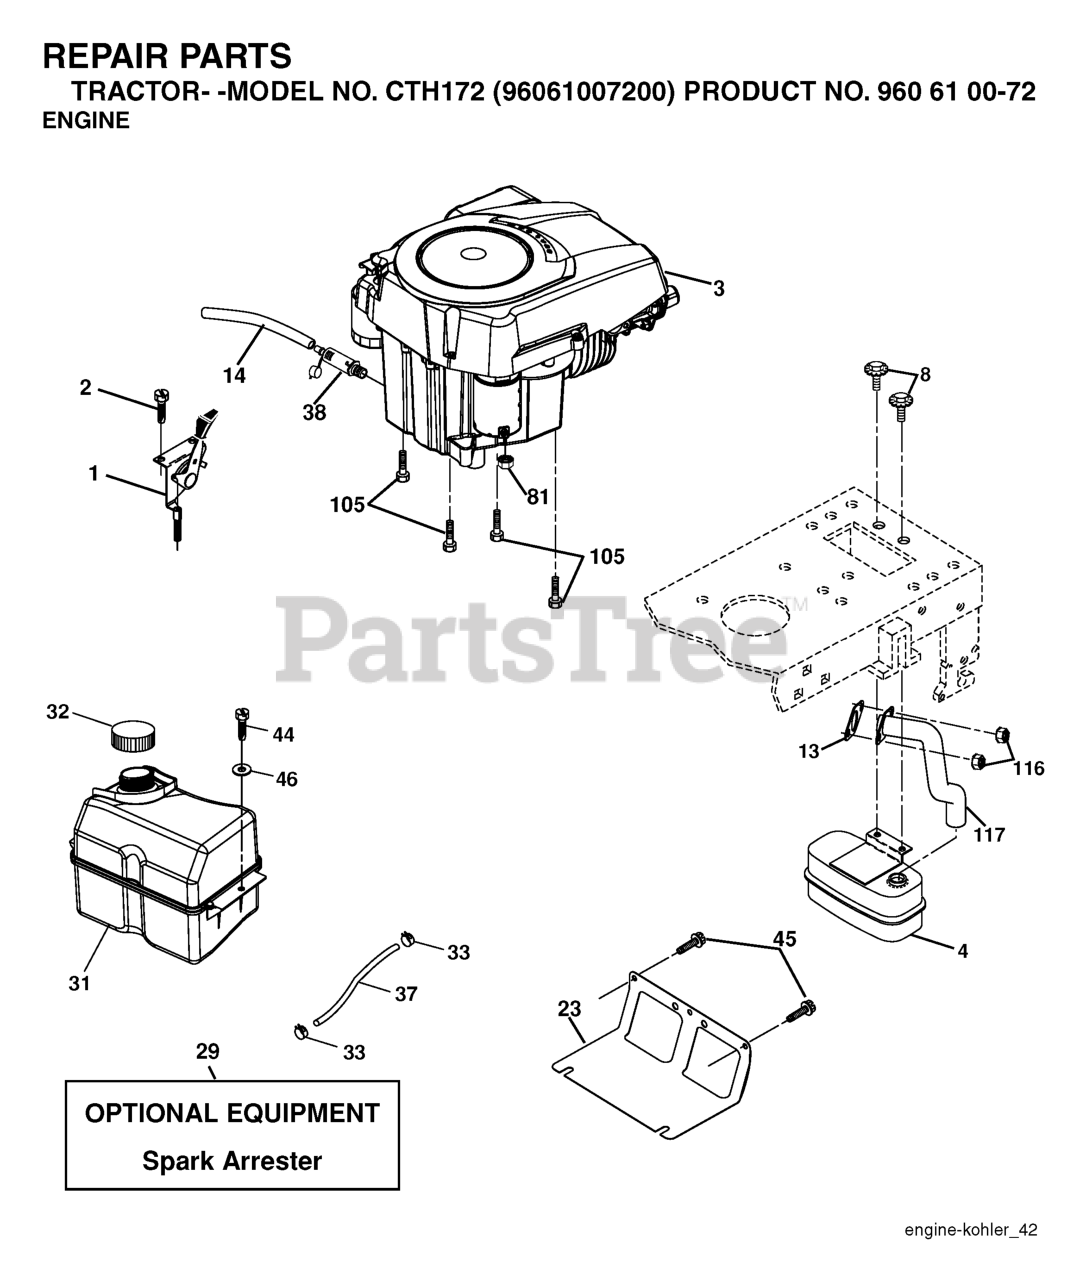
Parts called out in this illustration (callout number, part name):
1	CONTROL.THROTTLE.LT/YT
2	SCREW
4	MUFFLER.SINGLE.CYL.KOHL/B&S
8	BOLT.5/16-18UNCX3/4 W/SEMS.BLK
13	GASKET.EXHAUST.KOHLER
14	TUBE, DRAIN OIL ASM.
23	SHIELD.BROWNING.DBR.GUARD
29	KIT.SPARK ARRESTOR 794945 B&S
31	TANK FUEL
32	FUEL CAP
33	HOSE CLAMP
37	LINE.FUEL.20
38	PLUG DRAIN OIL EASY
44	SCREW HEXWSHR 1/4-20X3/4
45	SCREW, 3/8-16X3/4
81	NUT
105	SCREW 3/8-16X1
116	NUT.HEX.FLANGE.TOPLOCK
117	RP.TUBE.EXHAUST.KOHL.COURAGE
